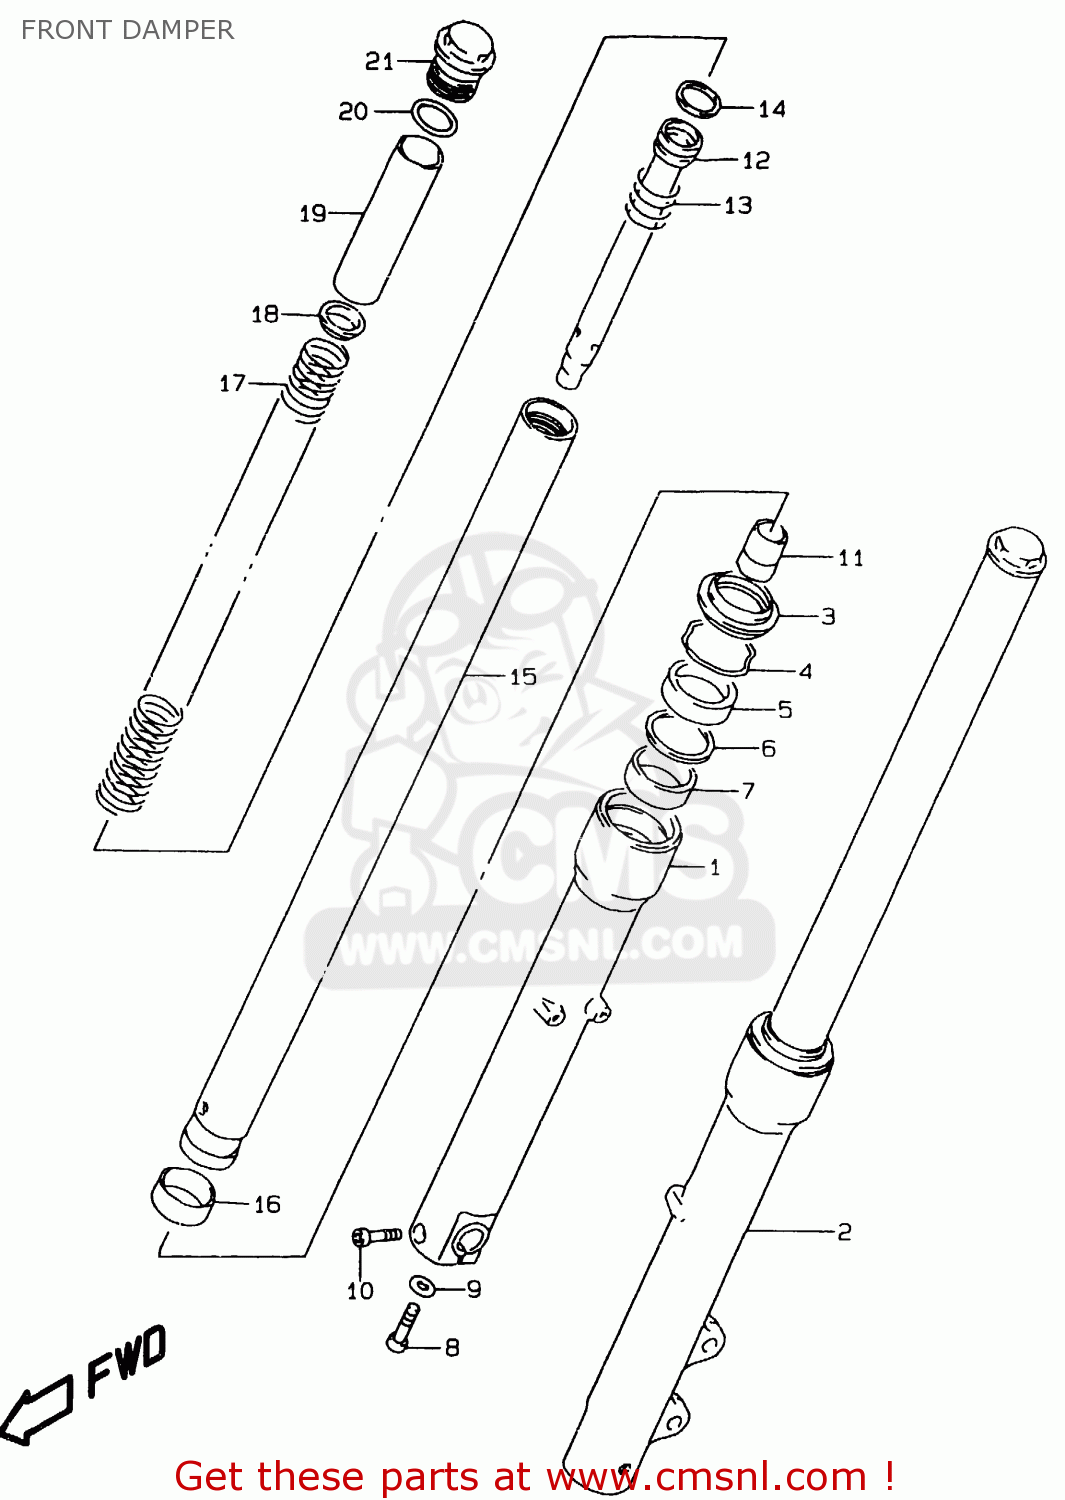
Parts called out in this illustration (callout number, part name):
1	TUBE,OUTER,R
2	TUBE,OUTER,L
3	SEAL,DUST
4	RING,STOPPER
5	SEAL,OIL
6	WASHER(40X50X2.3)
7	METAL,SLIDE
8	BOLT,FORK CYLINDER(10X25)
9	GASKET (NAS)
10	BOLT
11	PIECE,OIL LOCK
12	CYLINDER
13	SPRING,REBOUND
14	RING,PISTON
15	TUBE,INNER
16	PISTON
17	SPRING
18	WASHER
19	SPACER,SPRING
20	O RING
21	CAP
